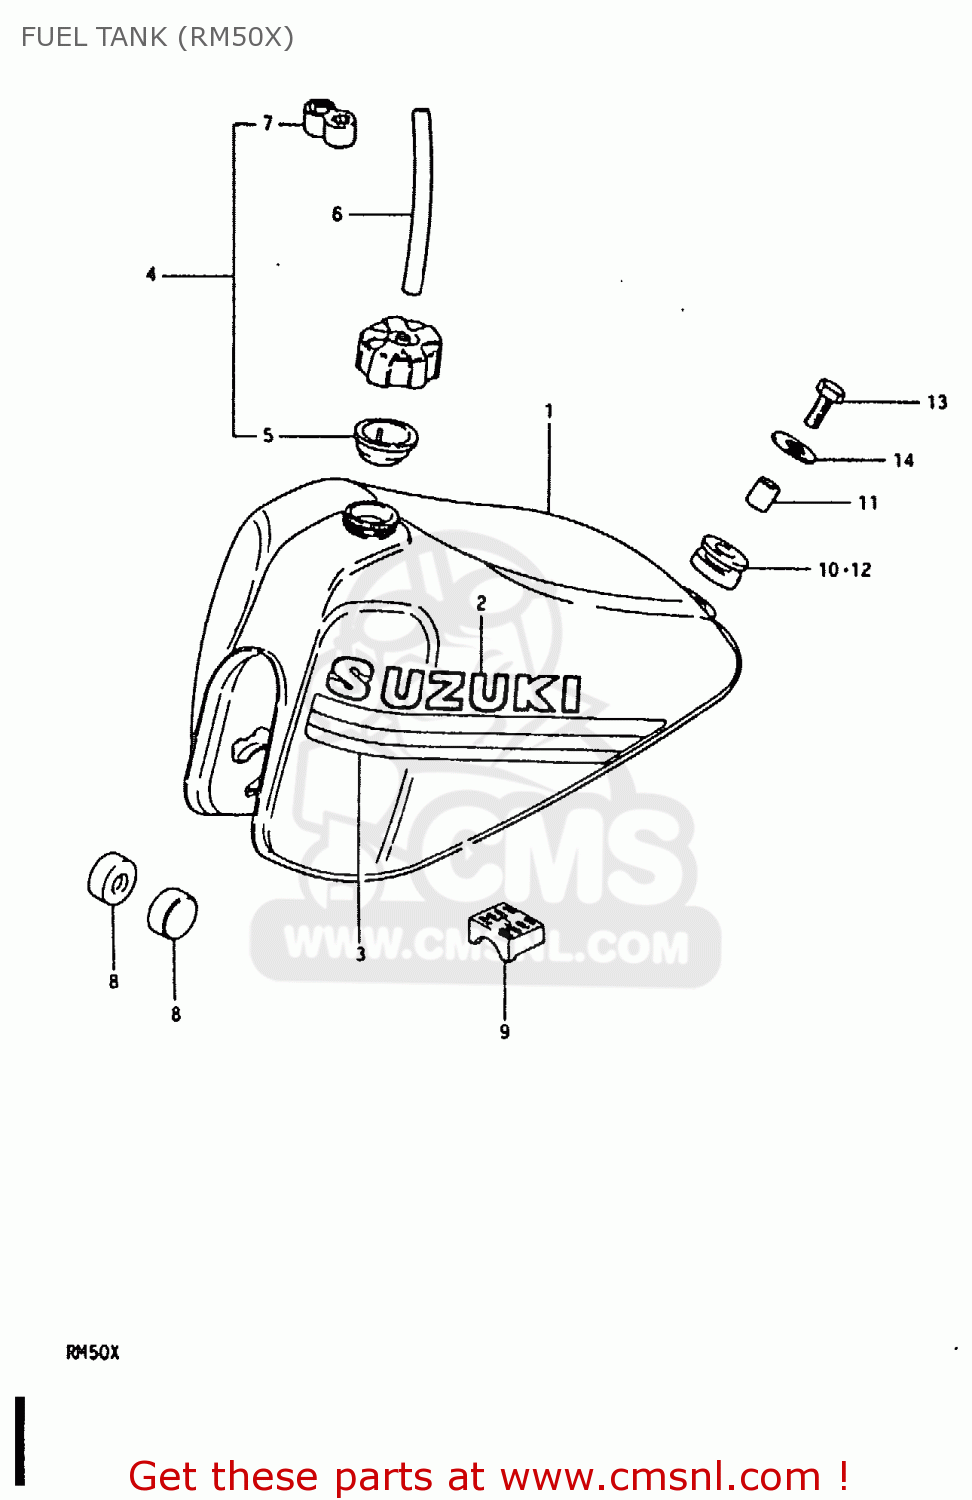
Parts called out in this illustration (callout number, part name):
1	TANK, FUEL (YELLOW)
2	EMBLEM
3	TAPE SET, STRIPING
4	CAP ASSEMBLY,FUEL TANK
5	GASKET,FUEL TANK CAP
6	HOSE
7	CLAMP,FUEL TANK BREATHER HOSE
8	CUSHION
9	CUSHION,FUEL TANK
10	CUSHION
11	SPACER (8.8X12X13.5)
12	CUSHION
13	BOLT
14	WASHER (8.5X29X1.6)
